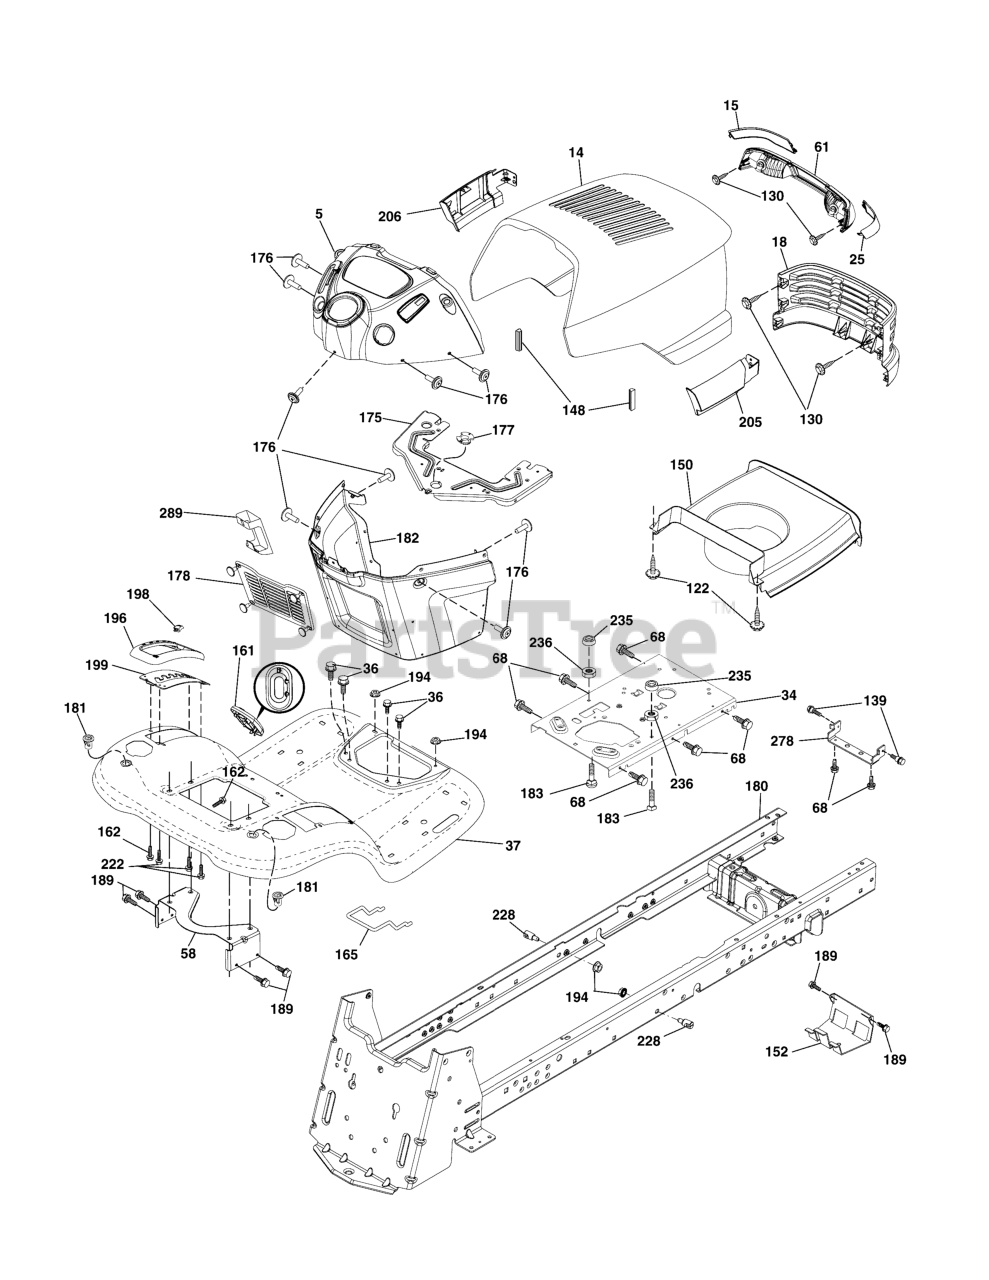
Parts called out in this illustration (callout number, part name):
15	Lens LH
18	Grille
25	Lens RH
34	Plate Engine
36	Screw 5/16-18 x 3/4
37	Fender
58	Bracket Support Fender
61	Lightbox Asm.
68	Screw 5/16-18 x 1/2
122	Screw WSHD Hex 10-32 x 5/8
130	Screw 10 x .750 BOS Thread
139	Bolt Shoulder 5/16-18
148	Bumper Extrusion
150	Air Duct
152	Shield Browning
161	Window Fuel
162	Screw
165	Support Tank Rear
175	Crossmember
176	Screw 10-24 x 5/8
177	Bushing Steering
178	Cargo Asm. Net
180	Chassis
181	Bushing Mtg. Fender Crgo
182	Dash Lower
183	Bolt 5/16-18 x 1-1/4
189	Screw 5/16-18 x 3/4
194	Nut Lock Hex Flange 5/16-18
196	Console Asm. Deck Lift
198	Indicator Deck Lift
199	Plate Deck Lift
205	Skirt Hood RH
206	Skirt Hood LH
222	Screw 1/4-20 x 5/8
228	Stud Fastner
235	Spacer Fender
236	Nut Lock 5/16-18 unc
278	Bracket Hood/Muffler
289	Plug Cruise Phone
